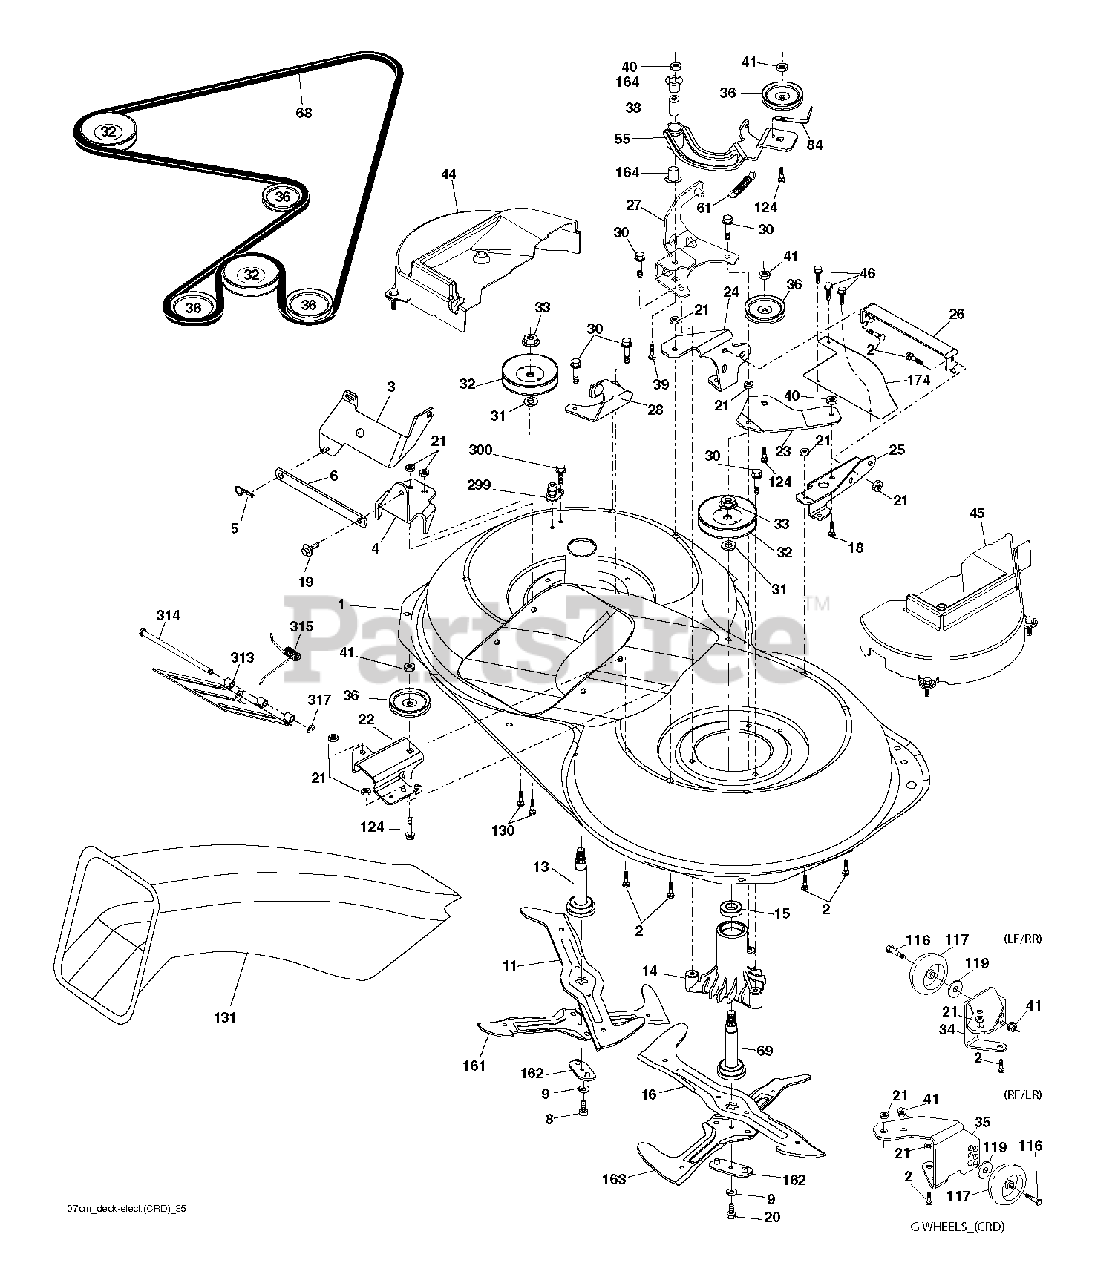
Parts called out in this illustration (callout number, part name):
2	BOLT
3	BRACKET.ASM.BAR.SWAY.CHASS
5	RETAINER-SPRNG RB
6	BAR SWAY
9	LOCKWASHER
11	BLADE.3N1.LH.CRD
13	SHAFT ASM VENT
14	HSG MANDREL
16	BLADE.3N1.RH.CRD
19	BOLT SHD 5/16-18
21	LOCKNUT
22	BRACKET
23	BRACKET
27	BRACKET
30	SCREW, WASHER HEAD
31	WASHER.SPACER.MANDREL
33	NUT.FLANGE.LOCK.TOP
36	PULLEY.IDLER.4.25
40	LOCKNUT
41	NUT LOCK FLG 3/8-16 UNC
46	SCREW.1/4-20X5/8
55	ARM IDLER
68	HEX-BELT 107 MOWER
69	SHAFT.ASM.W/LWR.BRG.RH.THREAD
84	KEEPER, BELT IDLER
116	BOLT.SHOULDER.3/8-16X3-5/8
117	WHEEL. GUAGE RALLY
124	BOLT.3/8-16X1.50
164	BRNG T
299	PORT.WASHOUT
317	E-RING.5/16"
